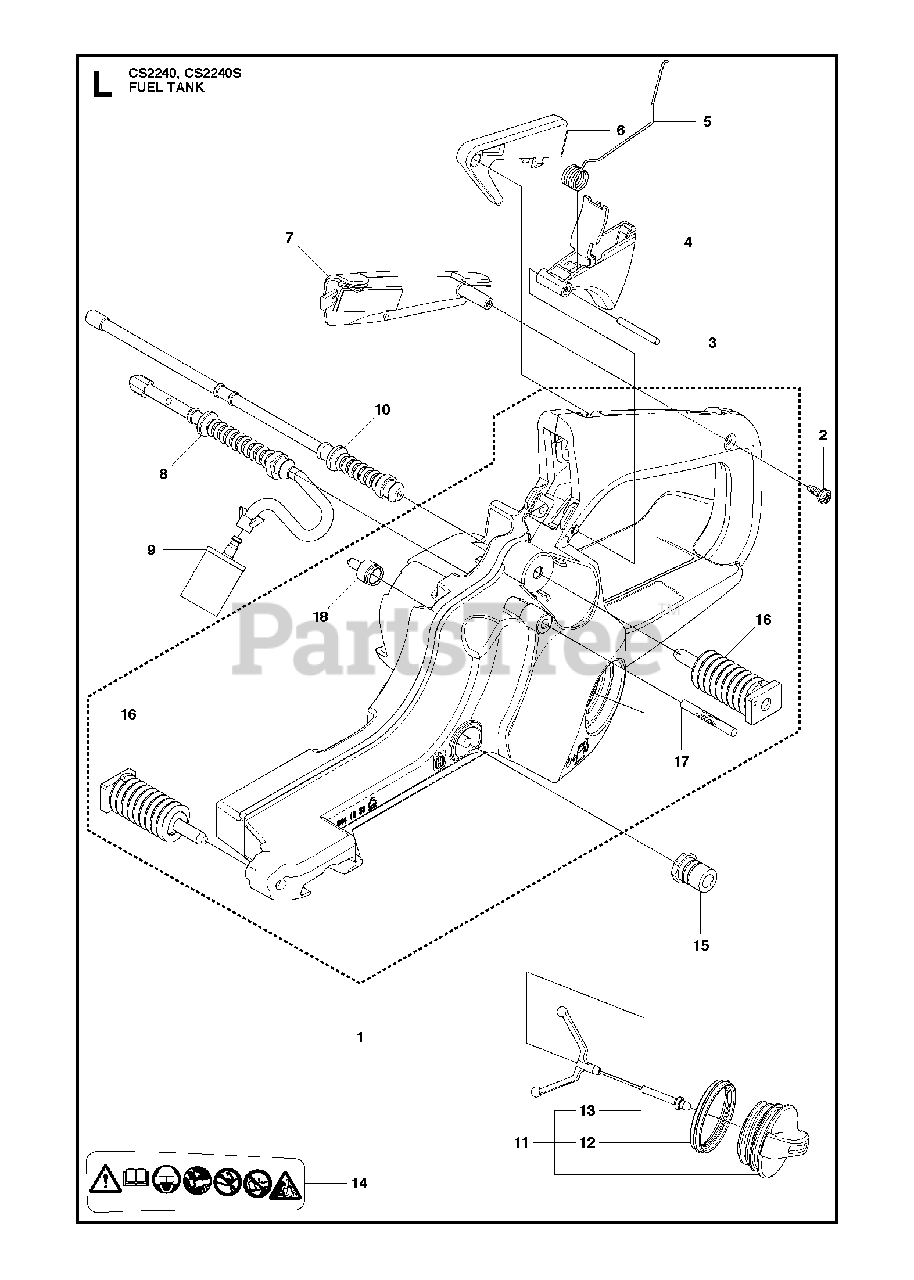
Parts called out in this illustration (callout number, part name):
1	FUEL TANK
4	THROTTLE CONTROL
6	THROTTLE LOCKOUT
7	HANDLE INSERT
8	FUEL HOSE
9	FUEL FILTER
10	RP RETURN HOSE
11	TANK CAP ASSY
12	SEALING
13	HOLDER
15	LATERAL SUPPORT
16	ANTIVIBRATION ELEMENT
17	GROOVED PIN
18	FUEL TANK VENT
